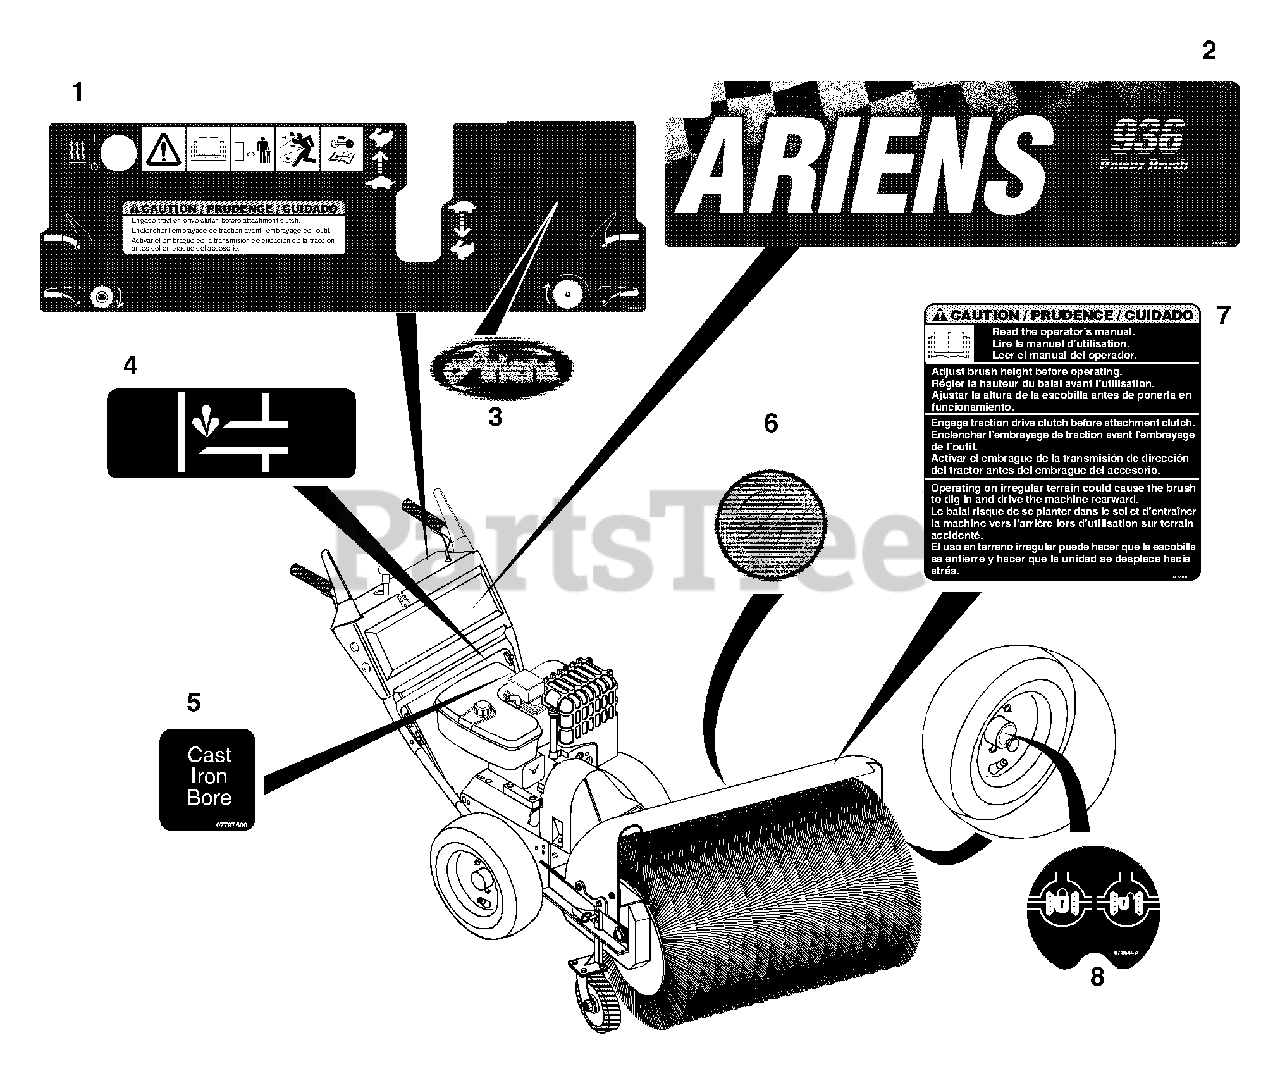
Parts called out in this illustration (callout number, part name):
1	DECAL - 936 DASH
2	DECAL - 936 FRONT PANEL
3	DECAL, "ARIENS" JEWEL
4	DECAL, PRIMER "TECUMSEH'S"
5	DECAL - CAST IRON BORE
6	DECAL, A+
7	DECAL, DANGER - POWER BRUSH
8	DIFFERENTIAL LOCK DECAL
